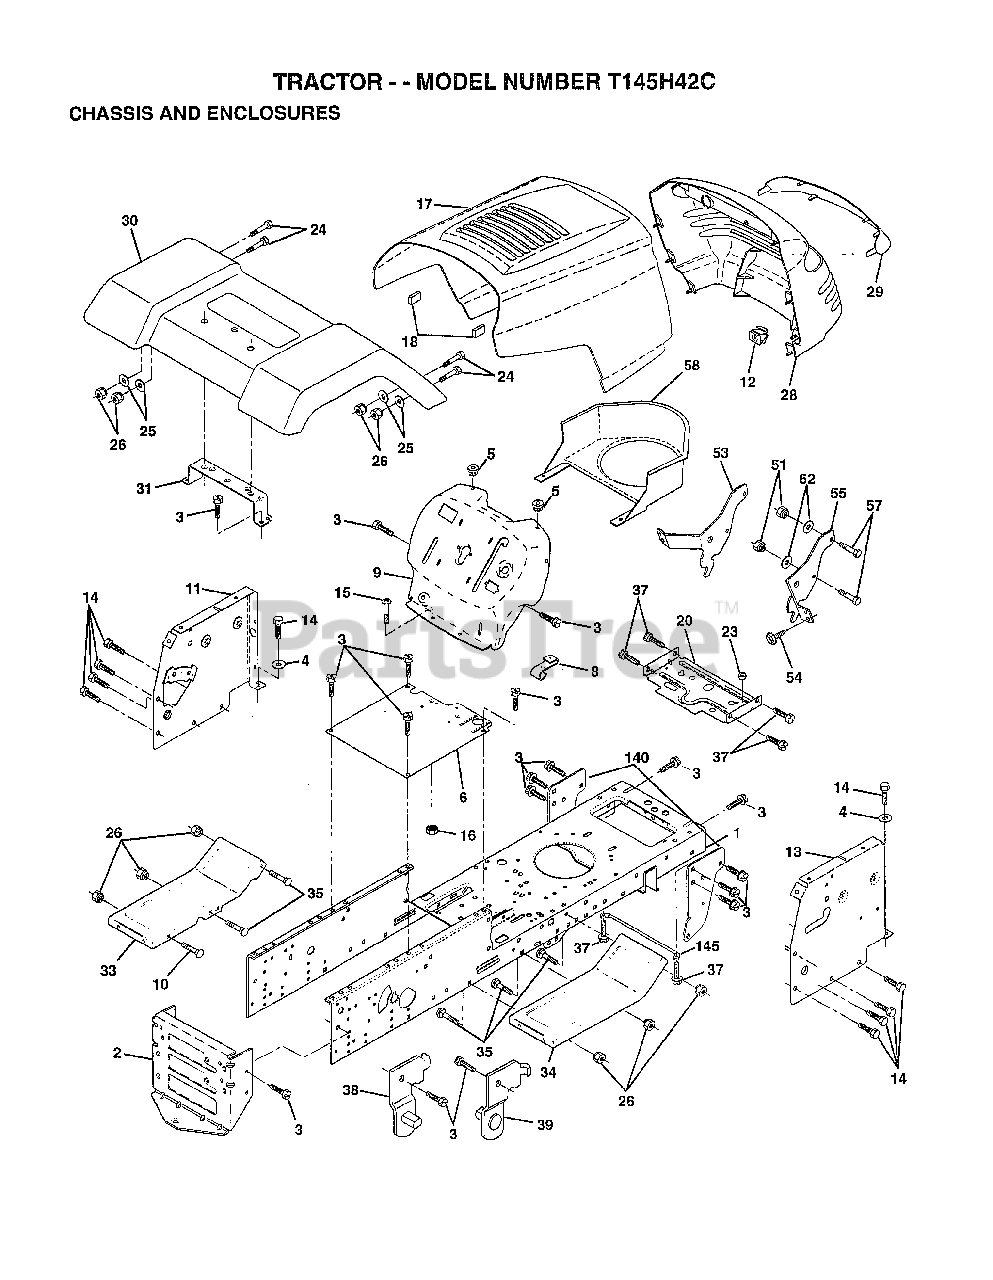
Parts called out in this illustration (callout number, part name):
3	SCREW
4	WASHER
5	BUMPER-HOOD/DASH
6	SADDLE
8	CLIP.RETAINER
9	DASH SILKSCREEN
11	"PANEL-DASH,LH"
12	CLIP.TINNERMAN
14	SCREW LT
15	SCREW
17	HOOD.STEEL.ASSY
20	"PLATE-MTG,BATT/FU"
24	BOLT
25	WASHER
26	NUT
28	GRILLE-MS428
29	LENS GRILLE
31	BRKT FENDER
33	FOOTREST.LH.LT/GT
34	FOOTREST.RH.LT/GT
35	BOLT
38	BRACKET ASM LH
39	BRACKET ASM RH
51	NUT
52	WASHER
53	BRACKET.GRILLE.LH
54	SCREW.HEX.WS.HD
55	BRACKET.GRILLE.RH
58	AIR DUCT
140	BRKT SUSPENSION
145	"ROD POVOT,CHASSIS"
